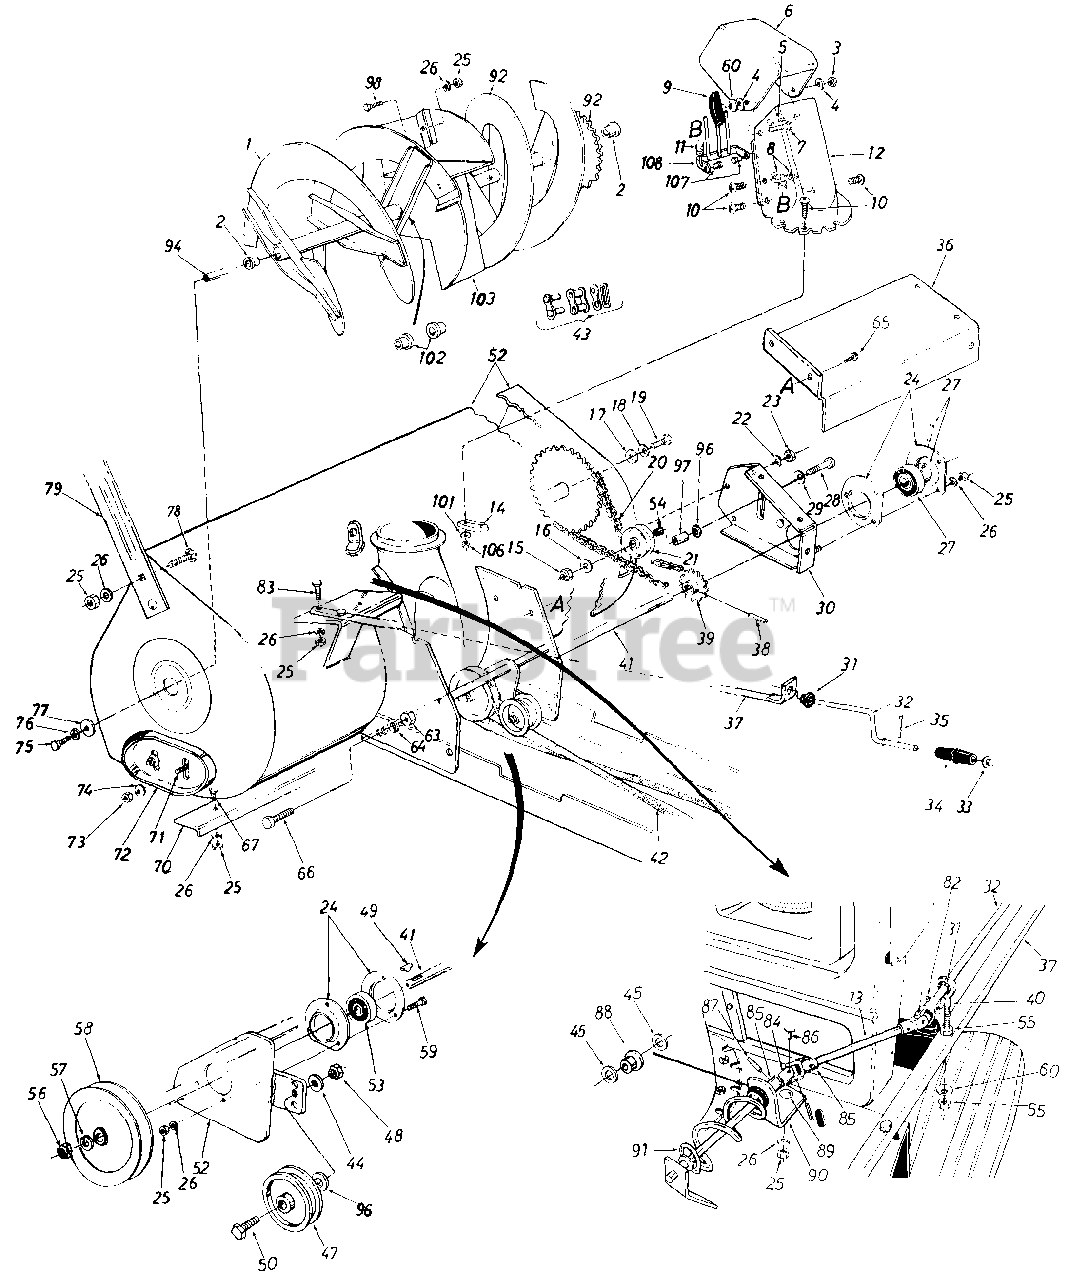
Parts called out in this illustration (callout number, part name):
3	Hex Cent. L.-Nut 5/16-18 Thd.
4	Fl.-Wash..344" I.D.
5	Truss Mach. Scr. 5/16-18 x .75" Lg.
6	Upper Chute
7	Carriage Bolt 5/16-18 x 1.0" Lg
8	Hex L-Nut 1/4-20 Thd.
9	Hand Knob
10	Truss Mach. Scr. 1/4-20 x .75" Lg.
11	Ext. Spring
12	Lower Chute
13	Chute Crank Extension Rod
14	Chute Flange Keeper
15	L.-Nut 3/8-16 Thd.
16	Fl.-Wash.
17	Fl.-Wash.
18	Belleville Wash.
19	Hex Bolt 1/2-13 x 1.00" Lg.
20	420 Chain 1/2" Pitch x 77 Links
21	Plastic Idler 2.00" O.D.
22	L.-Wash. 1/4" I.D.
23	Hex Nut 1/4-20 Thd.
24	Bearing Housing
25	Hex Nut 5/16-18 Thd.
26	L.-Wash. 5/16" I.D.
27	Self-Aligning Bearing
28	Hex Bolt 3/8-16 x 1.75" Lg.
29	Belleville Wash. 3/8" I.D.
32	Chute Crank .375 Dia. x 34.5" Lg.
33	Push Nut 3/8" Rod
34	Knob (Black)
35	Roll Pin
39	14 Teeth Sprocket Ass'y.
40	Eyebolt 5/16-18 x 3.0" Lg.
41	Drive Shaft
42	"V"-Belt
43	Meter Link for #420 Chain
45	Fl.-Wash..385 I.D. x .62" O.D.
47	Fl.-Idler with Flanges
48	Hex Jam L-Nut 3/8-16 Thd.
49	#61 Hi-Pro Key 3/16 x 5/8 Dia.
50	Hex Bolt 3/8-16 x 1.75" Lg.
52	Spiral Housing Ass'y.
53	Self-Aligning Bearing
54	Sleeve Bearing .50" I.D.
55	Hex Nut 5/16-18 Thd.
56	Hex Nut 3/4-10 Thd.
57	L.-Wash. 3/4" I.D.
58	"V"-Pulley .750" I.D. x 6.00" O.D.
59	Hex Sems Bolt 5/16-18 x .75" Lg.
60	Bell.-Wash..345" I.D. x .88" O.D.
63	Hex Nut 1/2-13 Thd.
64	L.Wash. 1/2" I.D.
65	Hex Wash, Hd. Tap Scr. 1/4-20 x .50" Lg.
66	Hex Bolt 1/2-13 x 2.75" Lg.
67	Carriage Bolt 5/16-18 x .75"
72	Skid Shoe
73	Hex Jam Nut 3/8-16 Thd.
74	Belleville Wash. 3/8" I.D.
75	Hex Bolt 1/2-13 x 1.00" Lg.
76	Belleville Wash. 1/2" I.D.
77	Fl.-Wash.
78	Carriage Bolt 5/16-19 x .62" Lg.
82	Cotter Pin
83	Hex Bolt 5/16-18 x 1.50" Lg.
84	Joint Block
85	Joint Bracket Ass'y.
86	Oval Head Rivet
87	Spring Pin Roll 1/8" Dia. x 75" Lg.
88	Nylon Bushing
89	Carriage Bolt 5/16-18 x .75" Lg.
90	Chute Crank Bracket
91	Chute Crank Ass'y.
96	Flat Washer
97	Idler Spacer
98	Carriage Bolt 5/16-18 x .75" Lg.
101	Fl.-Wash. 1/4" I.D.
102	Plastic Bushing
107	Shld. Nut 1/4-20 Thd.
